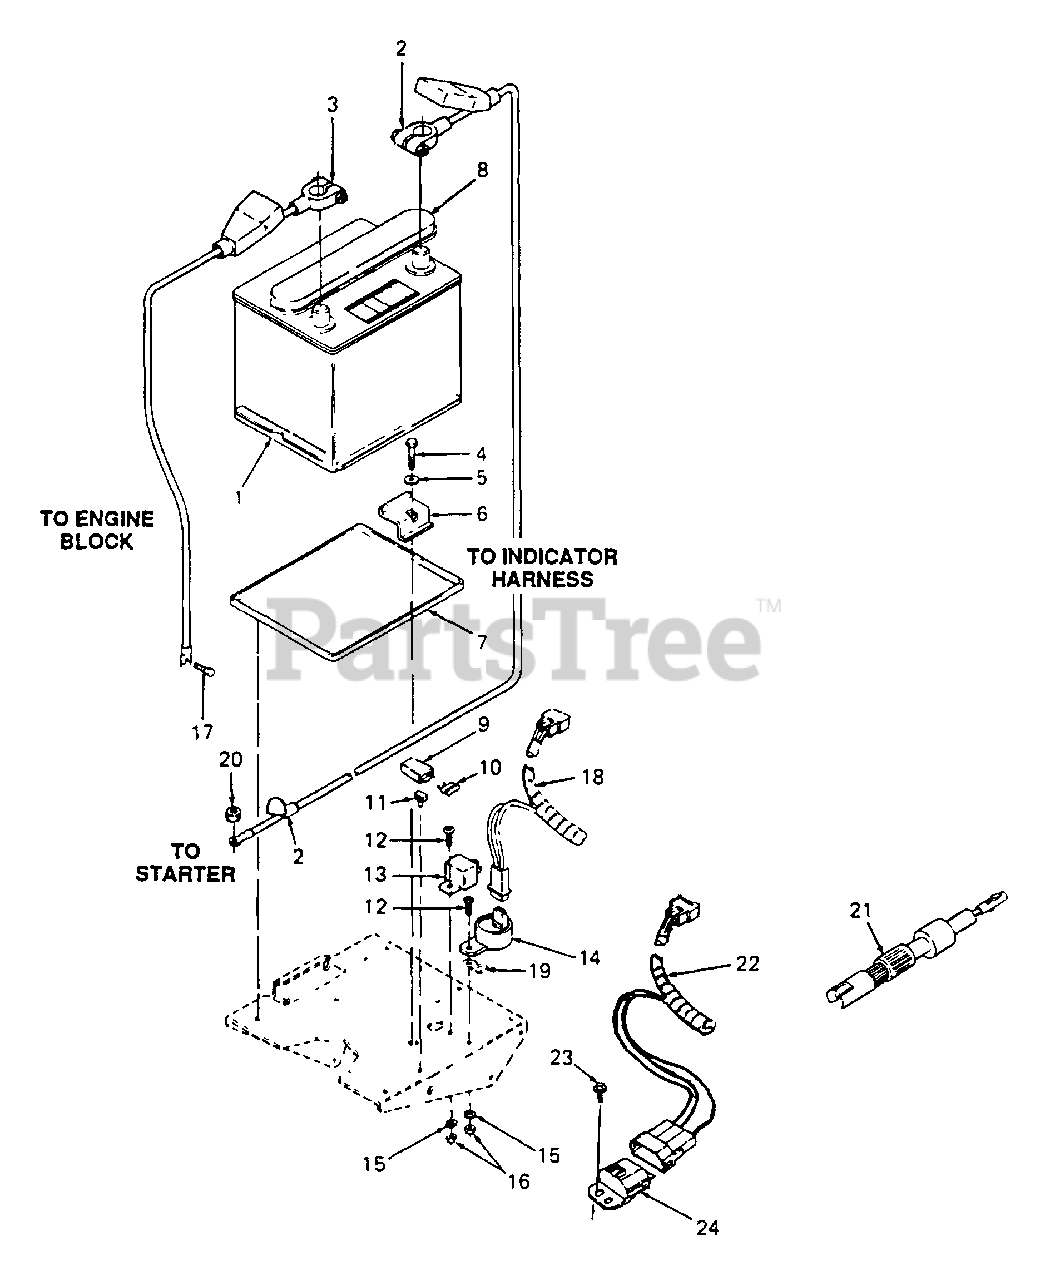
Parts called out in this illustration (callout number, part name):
1	Battery
2	Cable, Positive Battery
3	Cable, Negative Battery
4	Screw, Hex Cap, 5/16-18 x 1.38 Lg
5	Washer, Flat, .34 x .68 x .062 Thk
8	Cap, Battery Vent
9	Holder, Fuse
10	Fuse, 20 Amp
11	Clip, Fuse Holder Mtg
12	Screw, Truss Mach, #10-24 x .50 Lg
13	Relay
14	Indicator, Voltage
15	Washer, Lock, #10
16	Nut, Hex, #10-24
17	Screw, Hex Cap, M8-1.25 x 14 MM Lg
18	Harness, Main Wire
19	Lug, Quick Connect
20	Nut, Hex, M8-1.25 GR8.8
21	Diode Assy
22	Harness, Main Wire
23	Screw, Hex Wash Hd TT, 1/4-20 x .50 Lg
24	Module, Voltage Sensor
